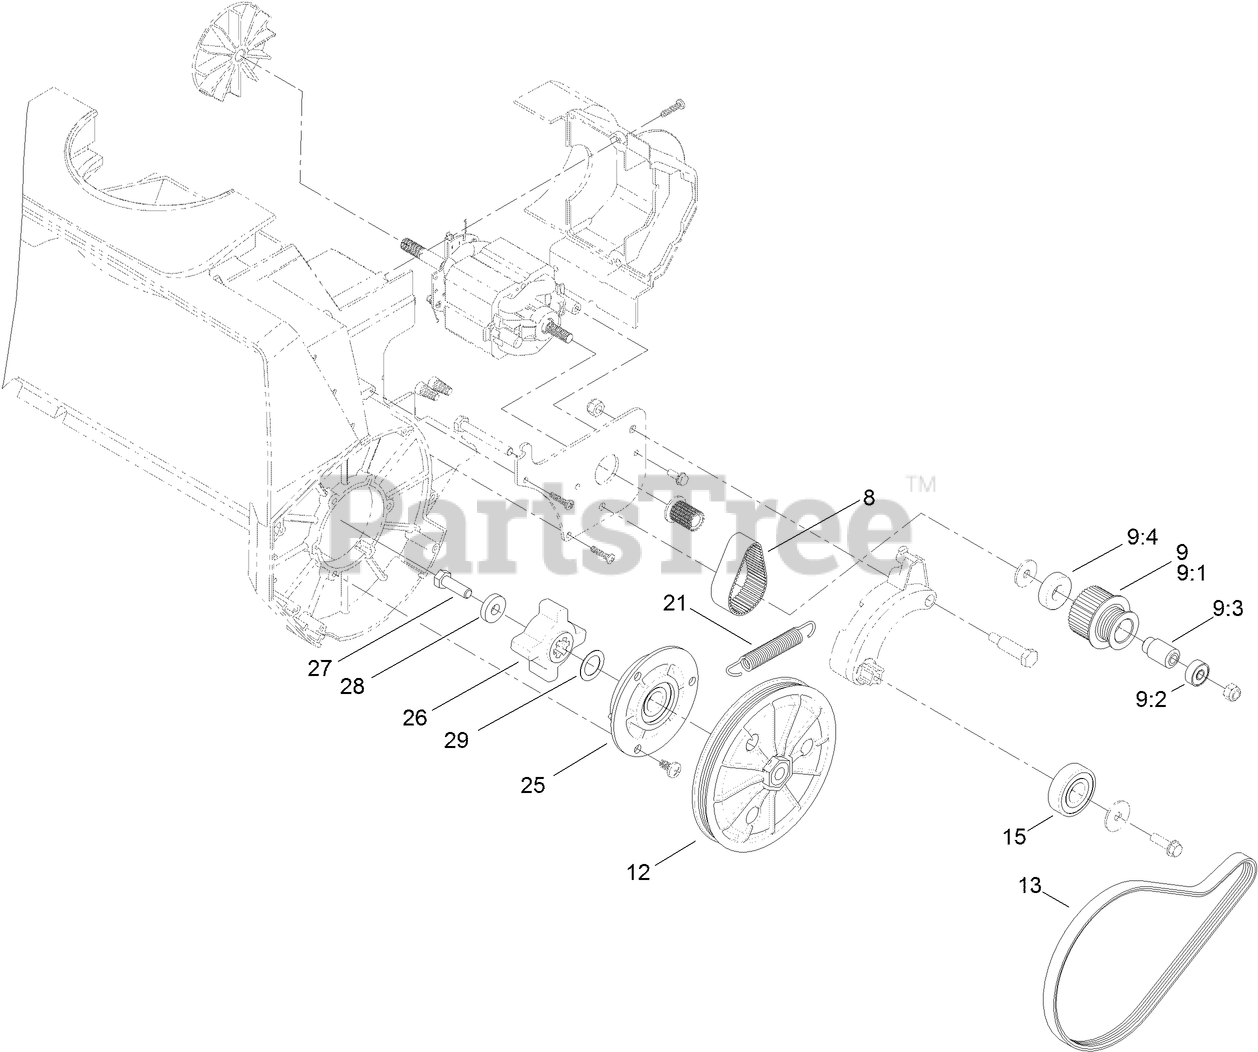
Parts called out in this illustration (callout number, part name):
8	BELT-PULLEY, IDLER/DRIVER
9	IDLER PULLEY ASM
9:1	PULLEY-IDLER
9:2	BEARING-BALL
9:3	SPACER-PULLEY, IDLER
9:4	BEARING-BALL
12	PULLEY ASM
13	BELT-DRIVE
21	SPRING-IDLER
25	PILLOW BLOCK ASM
26	COUPLER-PULLEY
29	WASHER-PLAIN
